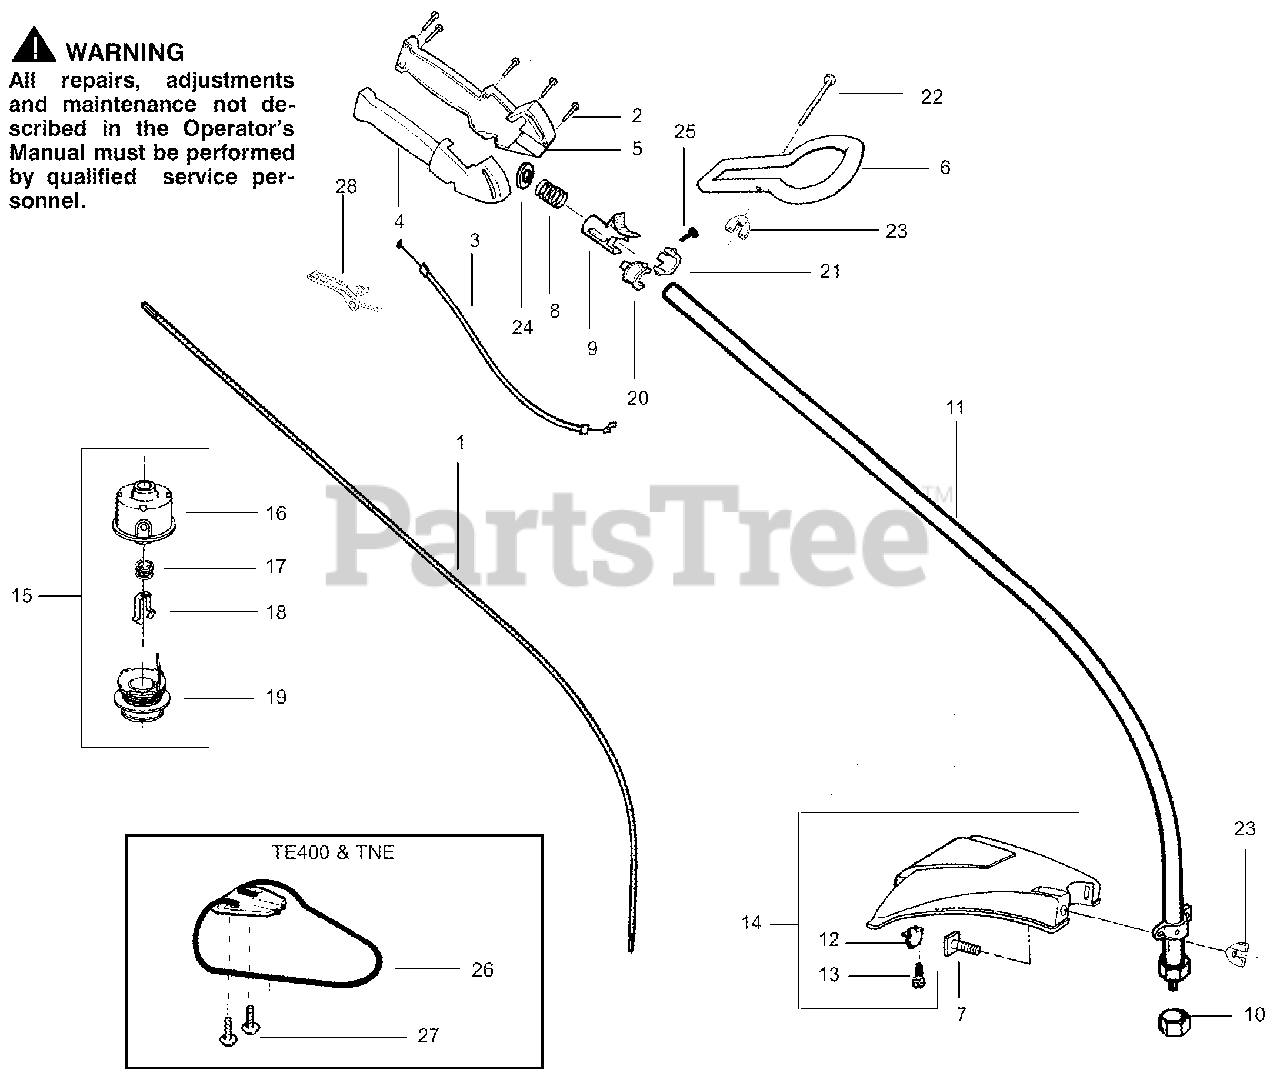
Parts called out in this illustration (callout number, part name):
1	Drive Shaft TNE, XT35, XT55,
1	Drive Shaft TE400, Ultratrim
3	Throttle Cable Ass'y.
4	Throttle Hsg. (Right)
5	Throttle Hsg. (Left)
6	Assist Handle
7	Bolt-Shield
8	Spring-Compression
9	Actuator
10	Dust Cup
11	Drive Shaft Hsg. Ass'y XT35, XT55, Ultratrim
11	Drive Shaft Hsg. Ass'y TE400
11	Drive Shaft Hsg. Ass'y TNE
12	Line Limiter
13	Screw-Line Limiter
14	Shield Kit Ass'y.
15	Cutting Head Ass'y.
16	Hub Ass'y
17	Spring-Return
18	Retainer-Spool
19	Spool w/Line
20	Locator-right
21	Locator-left
22	Bolt-Handle
23	Nut-Wing
25	Screw
26	Assy. wire form
